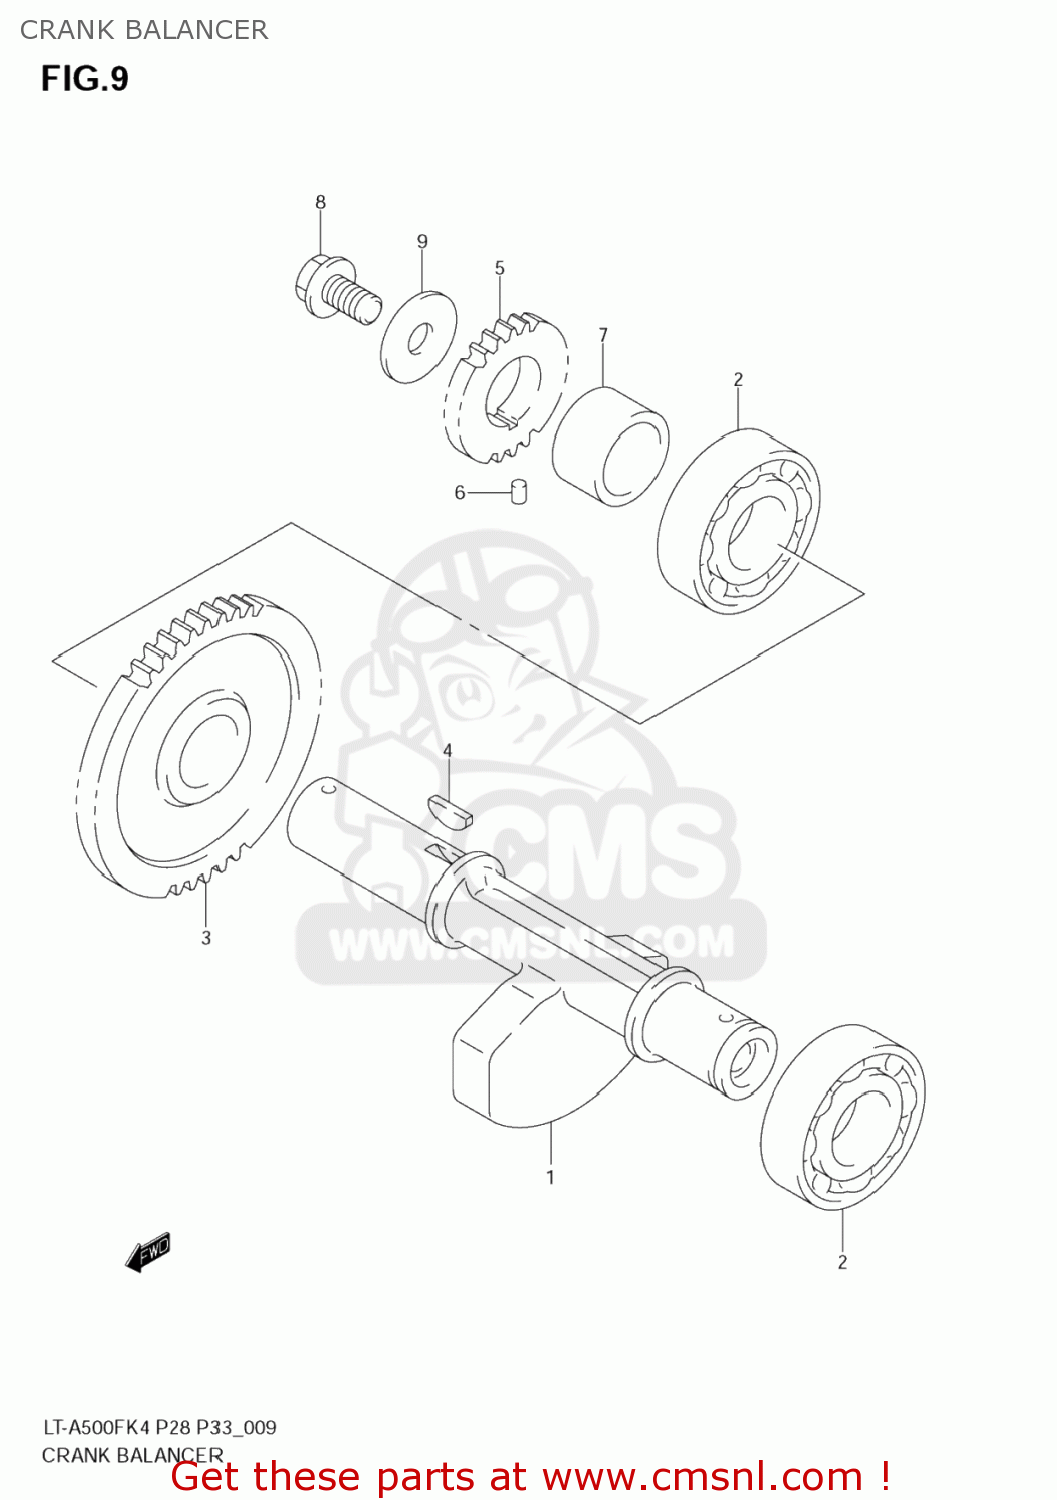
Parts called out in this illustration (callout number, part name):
1	BALANCER,CRANK
2	BEARING(22X56X16)
3	GEAR,CRANK BALANCER DRIVEN
4	KEY
5	GEAR,OIL PUMP DRIVE
6	PIN
7	SPACER,OIL PUMP DRIVE GEAR
8	BOLT(10X20)
9	WASHER
